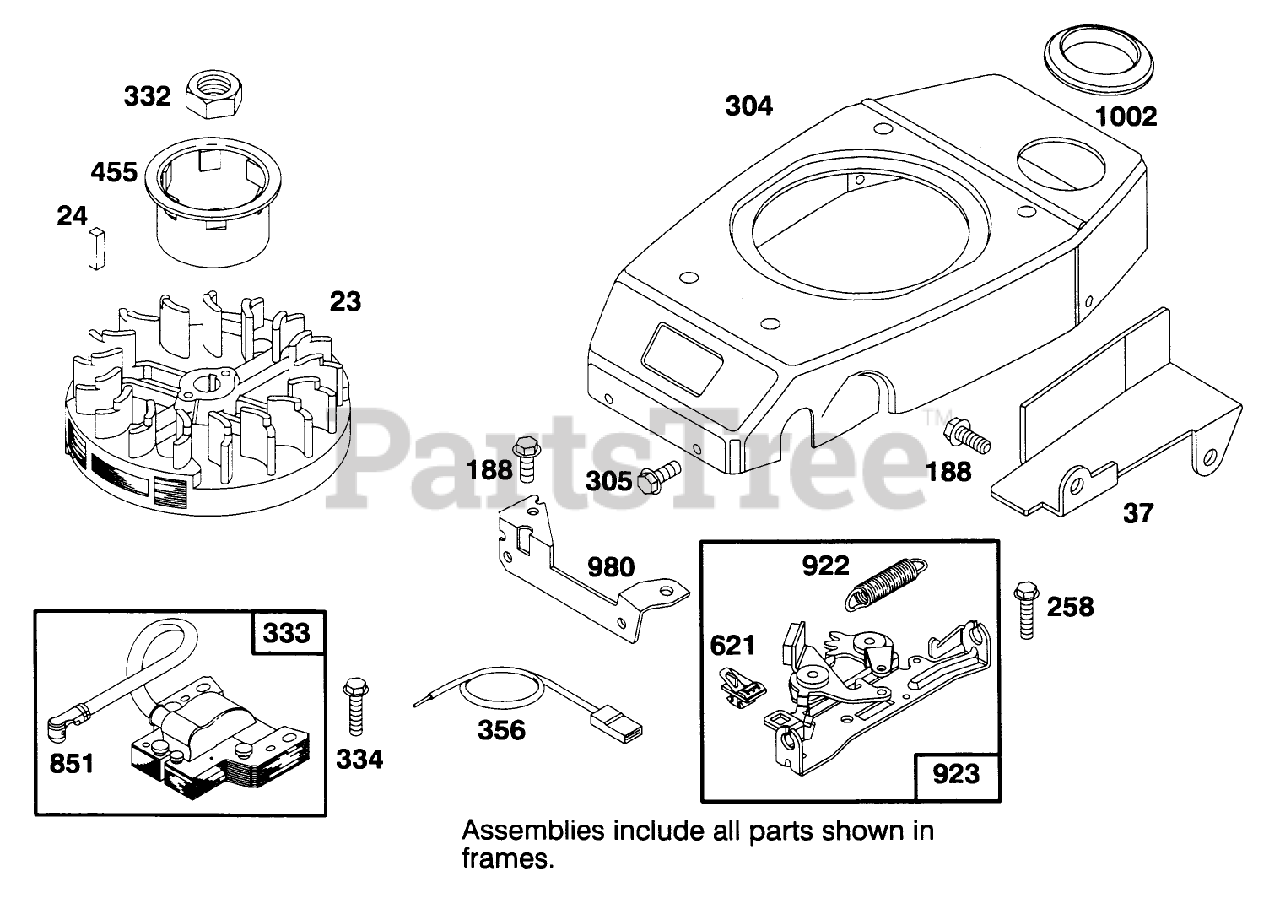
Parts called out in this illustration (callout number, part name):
24	KEY - FLYWHEEL
37	GUARD - FLYWHEEL
304	HOUSING - BLOWER
305	SCREW - HEX HEAD
332	NUT - HEXAGON
334	SCREW - SEM
356	WIRE - GROUND
621	STOP SWITCH
980	BRACKET-BLOWER HSG
